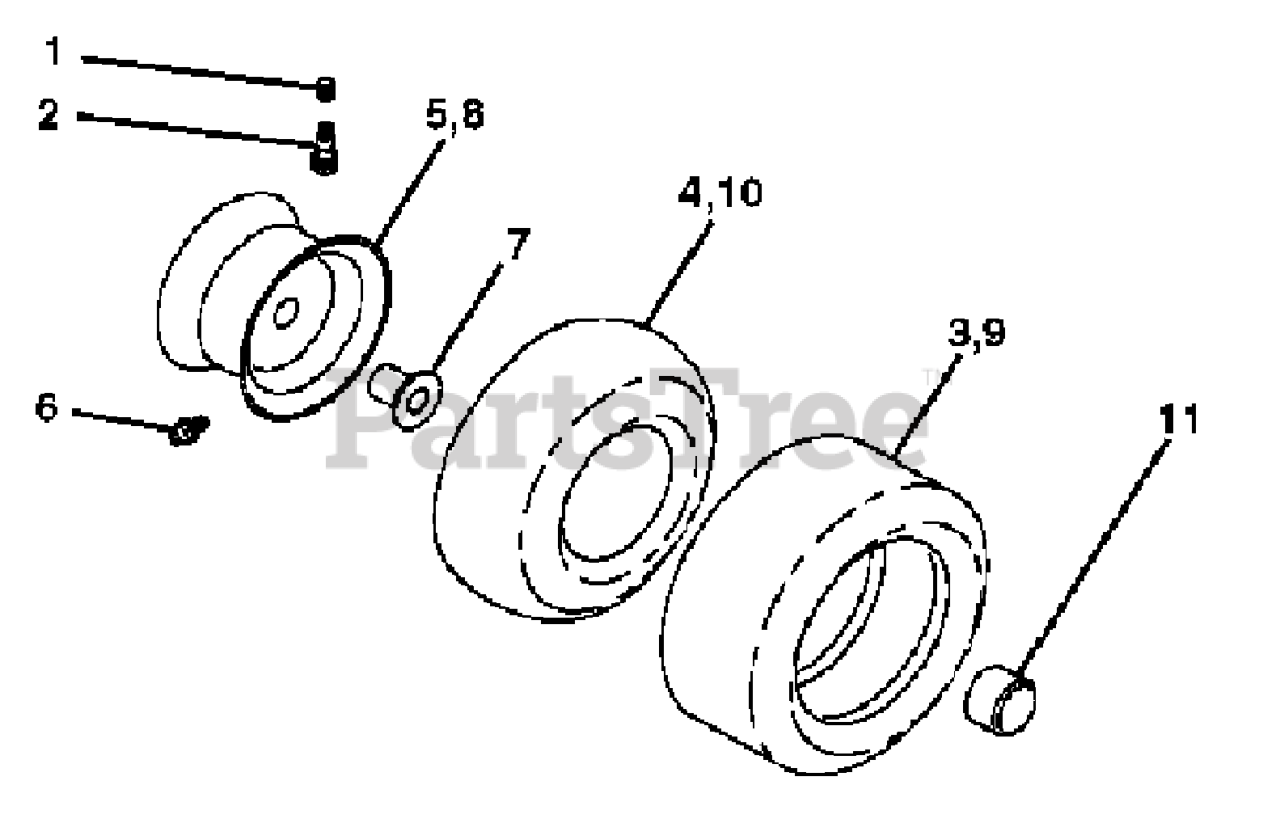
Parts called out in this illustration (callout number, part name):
2	VALVE STEM LT
3	TIRE HEAVY DUTY
4	TUBE.5.3/4.5/6
5	RIM ASM 6" FRONT SILVER
6	FITTING LT
7	BEARING T
8	RIM ASM 8" REAR SILVER
9	TIRE.TS.20X10-8
10	TUBE
11	CAP, AXLE BLK
